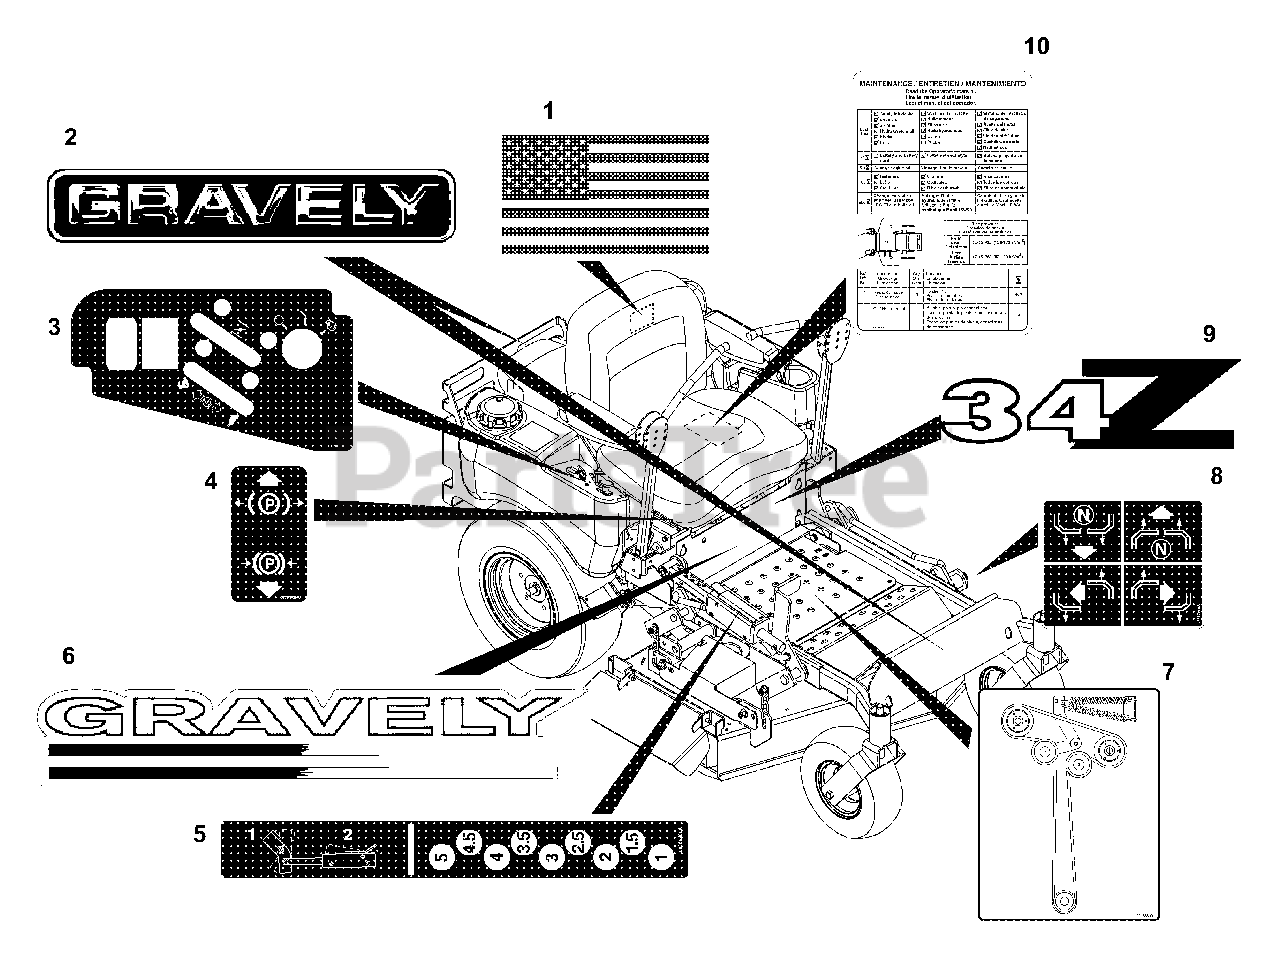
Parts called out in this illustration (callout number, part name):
1	Decal, American Flag
2	Decal, 15" Gravely Logo
3	Decal, Control Panel
4	Decal, Parking Brake Lever
5	Decal, Height of Cut
6	Decal, ZT Hood
7	Decal, Belt Diagram
8	Decal, Instructional Steering
9	Decal, PM 34Z
9	Decal, PM 44Z
10	Decal, Service Instructions
